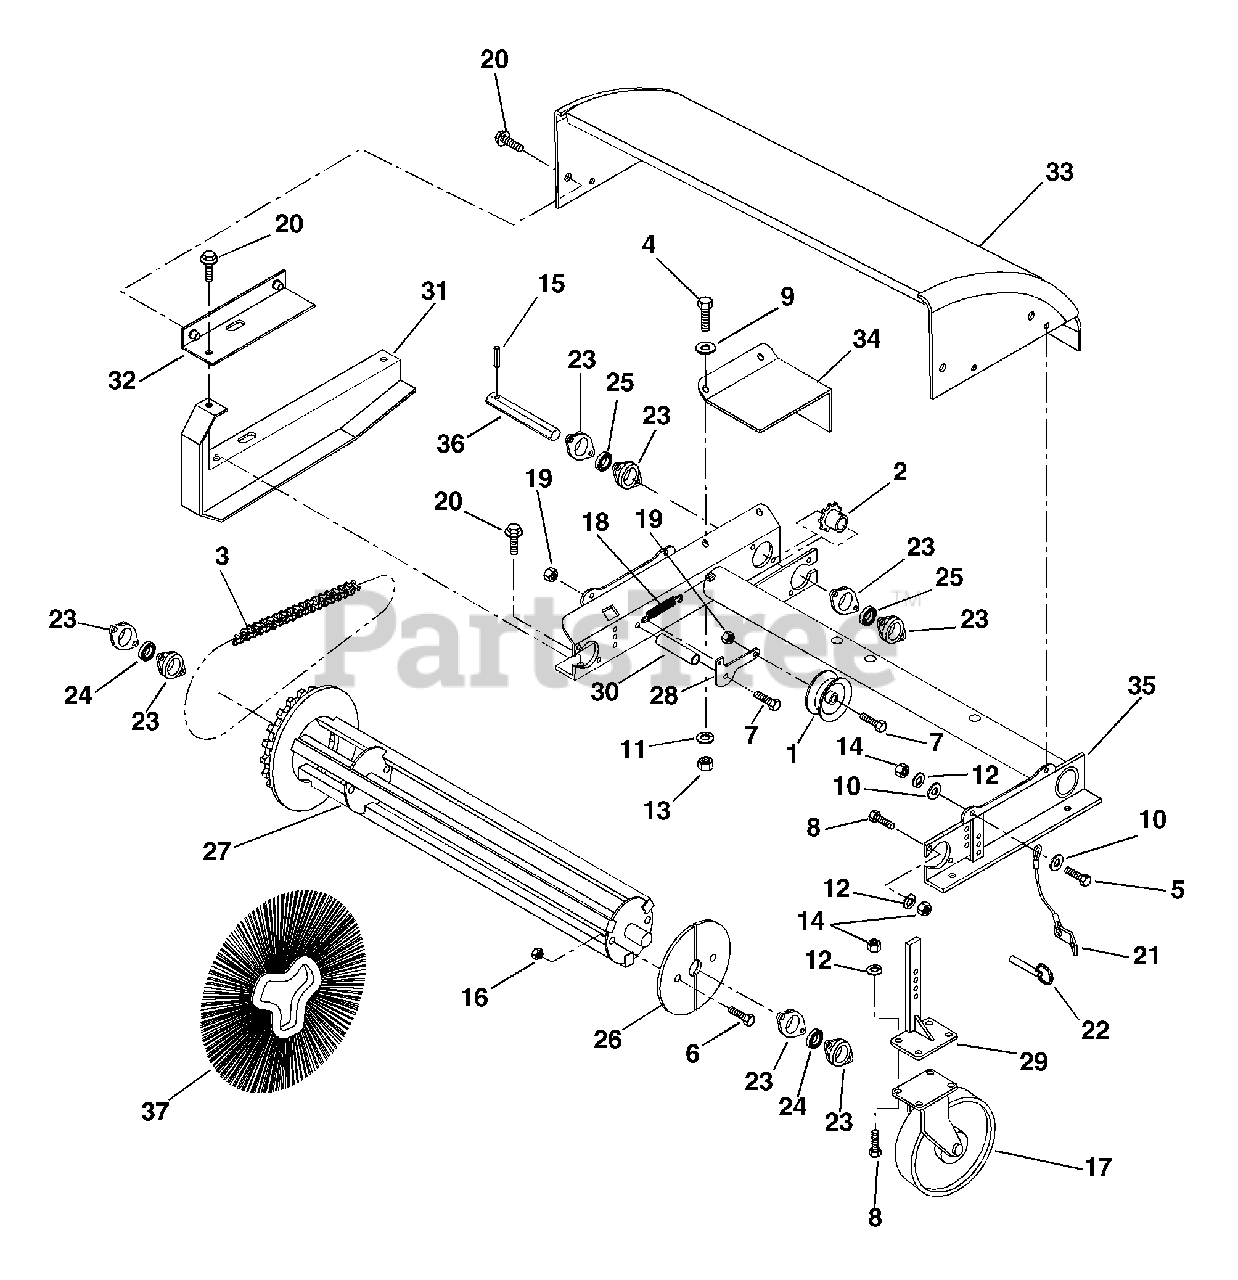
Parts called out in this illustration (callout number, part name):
1	CHAIN TIGHTENER
2	SPROCKET
3	CHAIN, ASS'Y #40X106 EDLS W/LK
4	@BLT-HEX .25-20X.75 GR5 YWZC
5	@BLT-HEX .31-18X1.00 GR5 YWZC
6	@BLT-HEX .31-18X2.25 GR5 YWZC
7	@BLT-HEX .38-16X1.50 GR5 YWZC
8	@BLT-HEX .31-18X.75 GR5 YWZC
9	@WSHR-FL-STL.281X.62X.065 YWZC
10	@WSHR-FL-STL.312X.734X.065 YWZ
11	@WSHR-LK .25X.062 REG YWZC
12	@WSHR-LK .31X.078 REG YWZC
13	@NUT-HEX .25-20 YWZC
14	@NUT-HEX .31-18 YWZC
15	PIN, SPRING LOK .187 X 1.25
16	NUT, LOK STAMPED .312-18 TINN.
17	WHL, 5 DIA.
18	SPRING, TENSION .50 X 3.0
19	@NUT-LK-CTR .38-16 YWZC
20	SCREW, GR 10.9 M6X1-20
21	LANYARD,.06 CAB.1.25X6,TYP C
22	PIN, HITCH, .38 X 2
23	FLANGE, SPHERICAL 2"
24	BRG 1.00 BORE, SPHER. OD.
25	BRG-BALL .884HEXX52MMX1.07
26	RETAINER PLATE (SET OF 2)
27	WELD, CORE C36TW
28	ARM, IDLER,BRM C36TW
29	WELD, CASTER LEG, C36TW
30	BSHG, .62X12 GA X.75
31	SHIELD,CHAIN, ARIENS
32	SHIELD, CHAIN,TOP,ARIENS
33	KIT, HD, ARIENS
34	SHIELD, INPUT, ARIENS
35	WELD, BFRM,ARIENS
36	SHAFT, HEX 20.5, W/HOLE
37	SET,SECTION,24",P,CONV.
